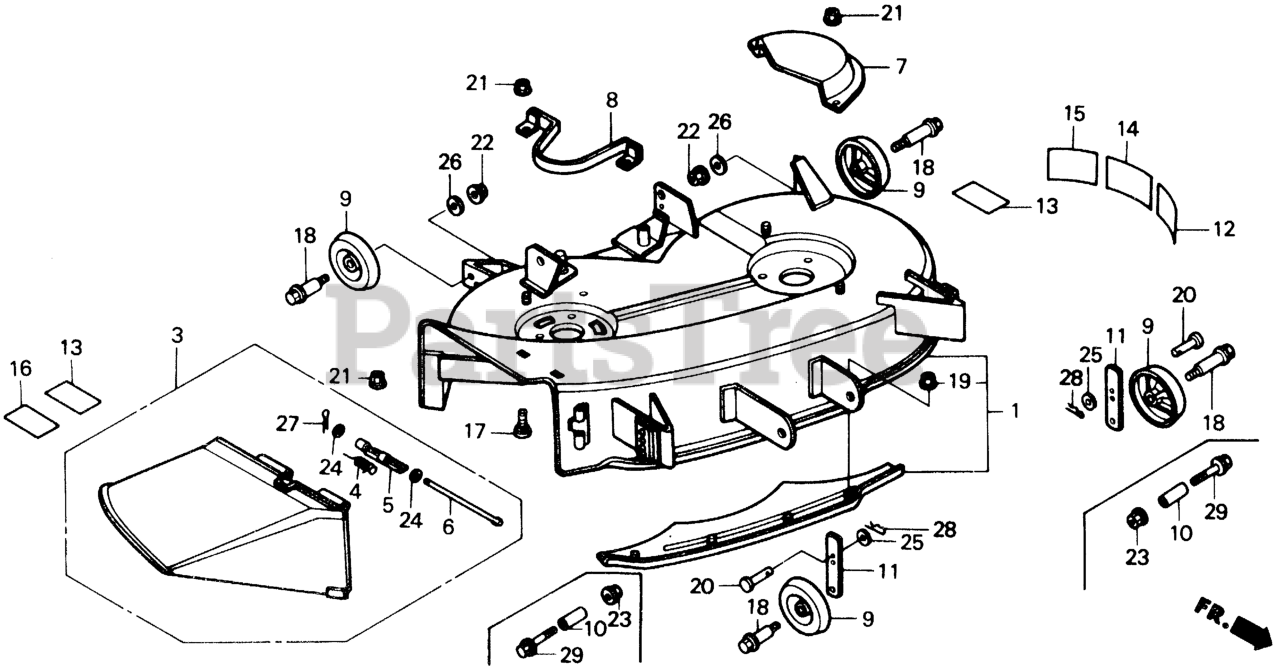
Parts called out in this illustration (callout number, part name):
1	HOUSING, CUTTER
2	PLATE, PROTECTOR *NH35M* (CLOUD SILVER METALLIC) (NOT AVAILABLE)
3	ADAPTER, DISCHARGE
4	SPRING, DISCHARGE ADAPTER
5	HINGE, DISCHARGE ADAPTER
6	PIN, DISCHARGE ADAPTER (NA USE ALT:06814-V09-A01)
7	COVER, L. BELT
8	STOPPER, BELT
9	ROLLER, ANTI-SCALP
10	COLLAR, ANTI-SCALP ROLLER (12.7X15.9X39.5)
11	ARM, ROLLER (12MM)
12	MARK, HEIGHT OPERATION (ENGLISH)
13	LABEL A, WARNING (ENGLISH)
14	MARK, INCH SIZE (38)
16	MARK, DANGER
17	BOLT, SPECIAL (9X15)
18	BOLT, ANTI-SCALP ROLLER
19	NUT, FLANGE (8MM)
20	PIN, ROLLER ARM (8X22)
21	NUT, FLANGE (8MM)
22	NUT, FLANGE (10MM)
23	NUT, FLANGE (12MM)
24	WASHER, PLAIN (6MM)
27	PIN, COTTER (2.0X15)
28	PIN, SNAP (7MM)
29	BOLT, FLANGE (12X60)
